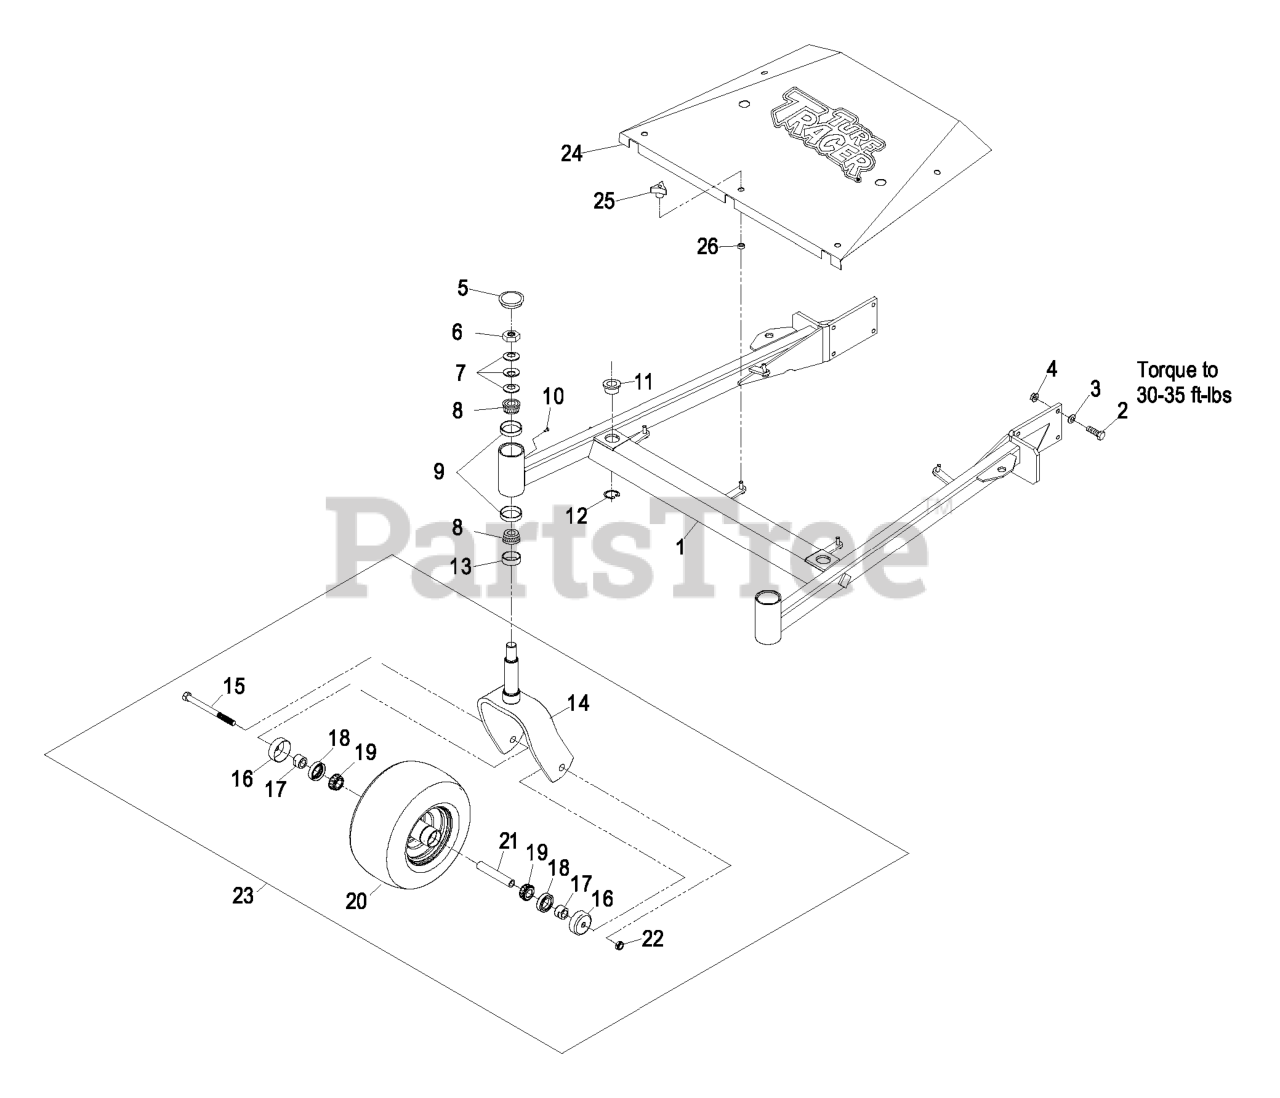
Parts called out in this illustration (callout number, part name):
1	ASM,524 FMD DK SUPPORT,SE
2	SCREW-HH
3	WASHER-BELLEVILLE
4	NUT-HHF, WHIZ
5	CAP-GREASE
6	NUT-LOCK, NI
7	WASHER-BELLVILLE
8	Cone-Bearing Tapered Roller
9	CUP-BEARING
11	BUSHING-DECK
12	RING-RETAINING
13	SEAL-GREASE
14	WLD, CASTER FORK
15	SCREW-HH
16	GUARD-SEAL
17	SPACER-NUT
18	SEAL-CASTER
19	BEARING-CONE, TAPERED ROLLER
22	NUT-HEX
25	KNOB-3 PRONG
